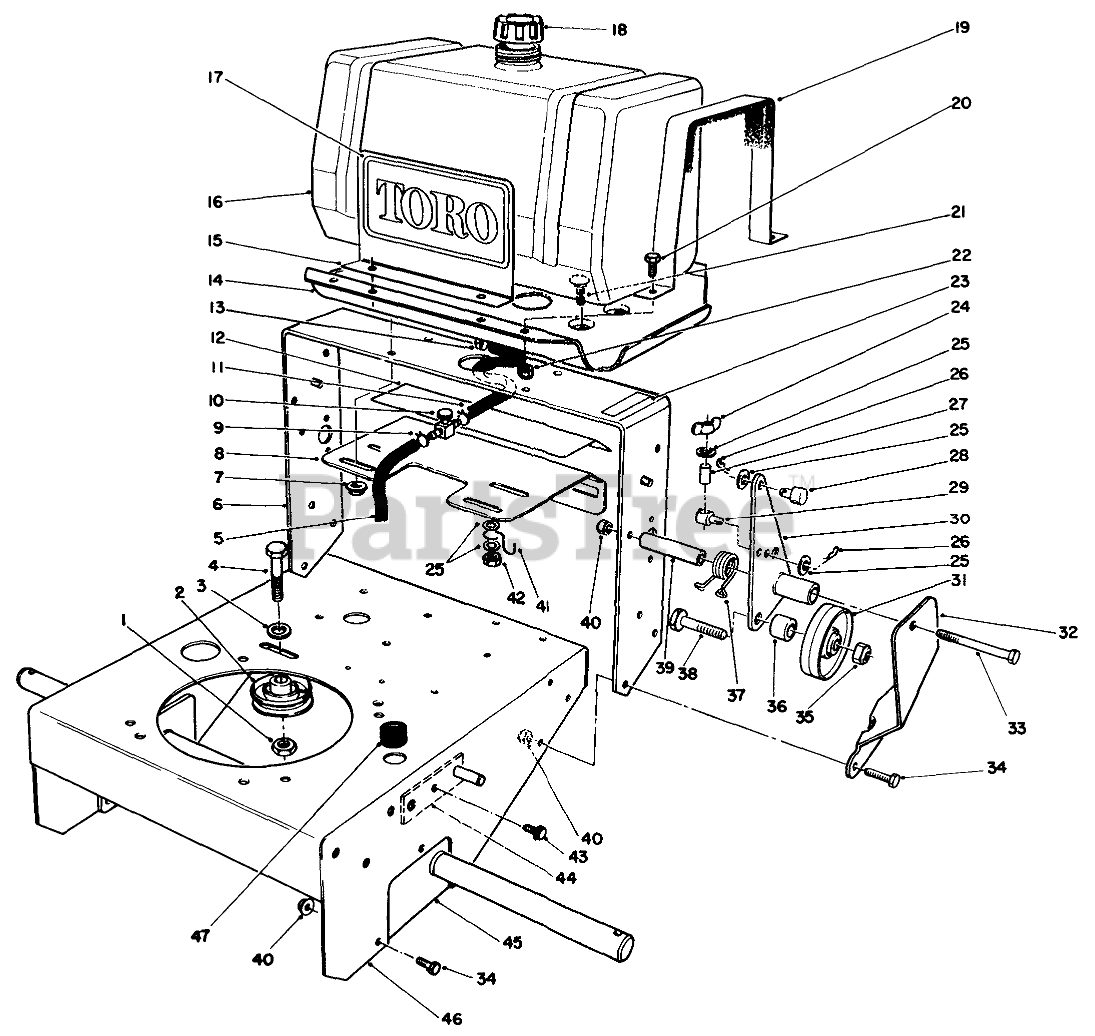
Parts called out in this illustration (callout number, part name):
1	NUT-HF
2	PULLEY-IDLER
3	WASHER-FLAT
4	SCREW-HH
5	HOSE-FUEL
6	Frame-Rear
7	NUT-HF
8	Plate
9	CLAMP-HOSE
10	FUEL VALVE
11	HOSE-FUEL
12	Decal-Ground Speed
13	CLAMP-HOSE
14	PLATE-FUEL TANK
15	DECAL-PLATE
16	TANK-FUEL
17	DECAL
18	GAS CAP ASM
19	STRAP ASM
20	SCREW-HH
21	SCREW-CARR
22	NUT-LOCK, NI
23	Decal-Fuel Shut Off
24	NUT-WING
25	WASHER-PLAIN
26	PIN-COTTER
27	BUSHING-NYLON
28	ROD FITTING
29	FITTING-ROD
30	Bracket-Idler, LH
31	IdlerWheel
32	Bracket-LH
33	SCREW-HH
34	SCREW-HH
35	NUT-LOCK, NI
36	WHEEL IDLER SPACER
37	SPRING-TORSION, LH
38	SCREW-LEVELER
39	PIVOT-IDLER SPACER
40	NUT-LOCK, NI
41	GAS LINE CLIP
42	NUT-LOCK, NI
43	SCREW-HHF
44	PIVOT POST WA
45	AXLE PLATE WA R
46	FRAME WA
47	GROMMET
